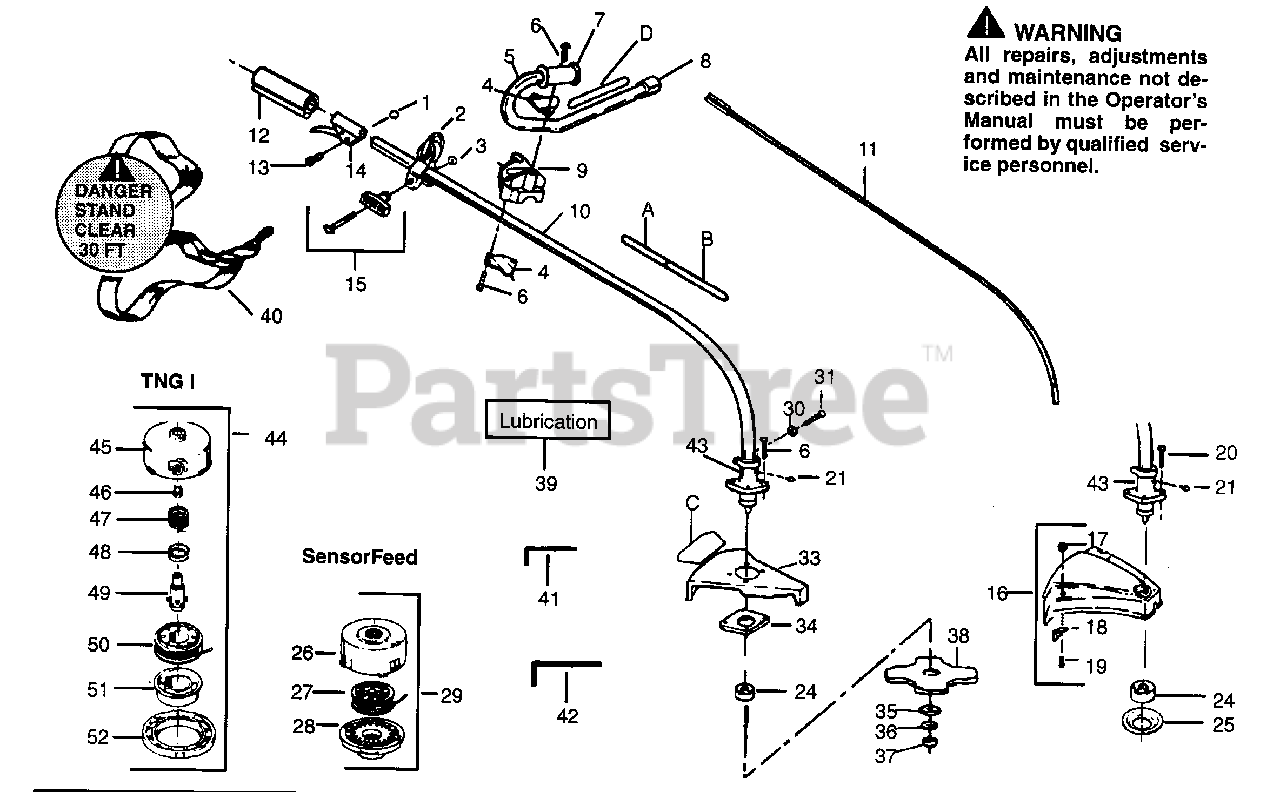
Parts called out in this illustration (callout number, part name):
2	Clamp Harness Ass'y.
4	Handlebar Bracket
5	Handlebar
7	Handlebar Grip
8	Handlebar Cap
9	Handlebar Clamp
10	Type 1 & 2
11	Drive Shaft
12	Drive Shaft Grip
14	Throttle Lever Ass'y. (Inc. 1 & 13)
15	"T" Handle Kit
16	Shield Kit Ass'y. (Inc. 17-19)
17	Locknut
18	Line Limiter
24	Dust Cup
25	Grass Washer
26	Hub Ass'y.
27	Spool w/Line
29	Cutting Head Ass'y (Inc. 26-28)
33	Shield
34	Shield Retention Plate
36	Washer
38	Weed Blade
39	Shaft Lubrication
40	Shoulder Strap
41	Hex Wrench (5/32)
42	Hex Wrench (3/16)
43	Bearing Hsg. Ass'y. (Inc. 21 & 24)
44	Cutting Head Ass'y. (Inc. 45-52)
45	Hub Ass'y.
46	Line Saver
48	Spring Cap
49	Drive Gear
50	Spool w/Line
51	Release Button
A	Decal-Shaft Warning-Upper
B	Type 1 & 2
C	Decal-Blade Direction (Not a serviceable part)
D	Decal-Handlebar
